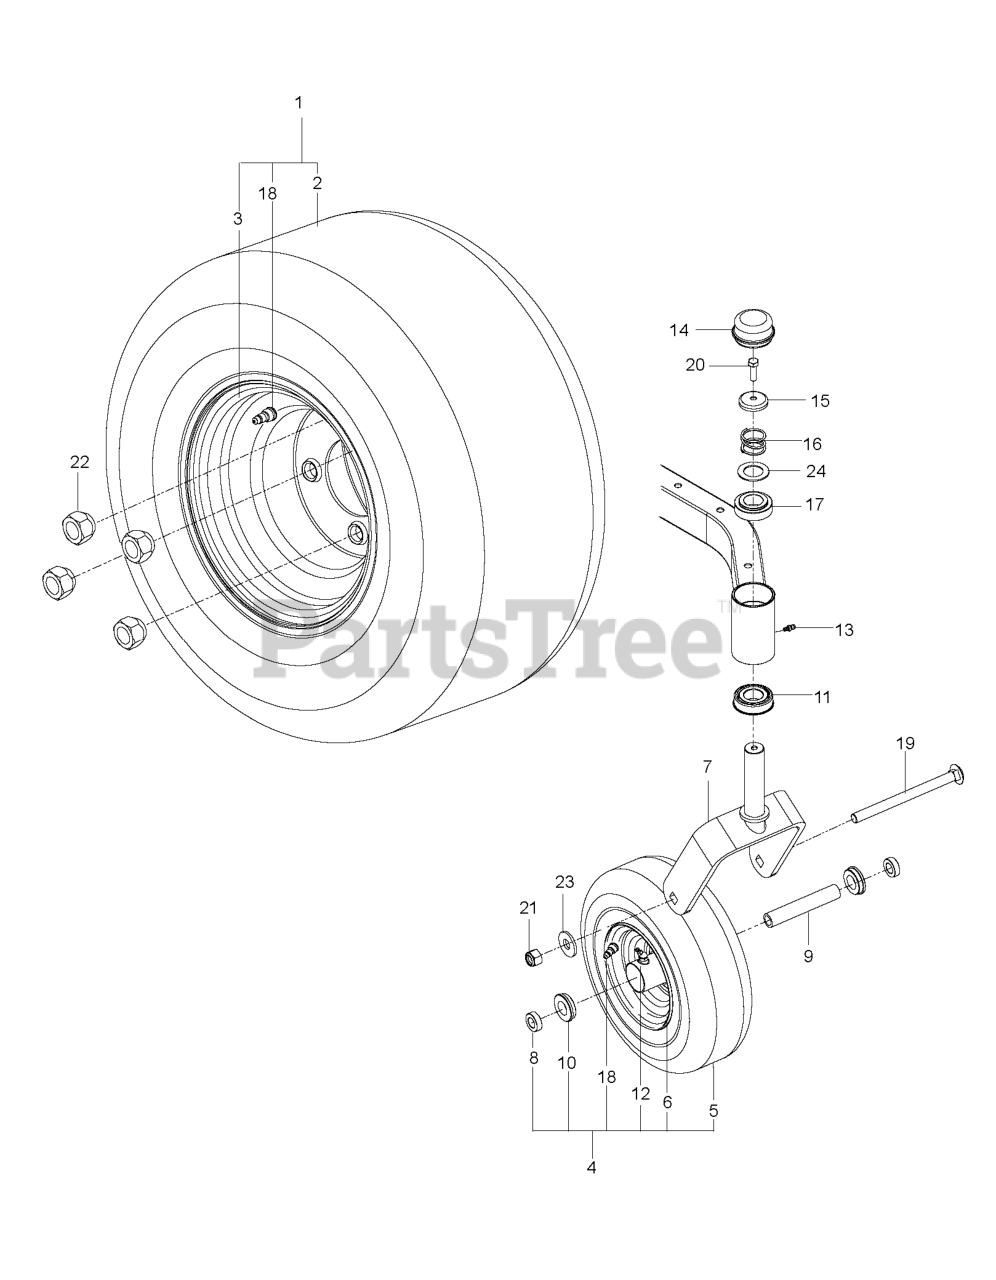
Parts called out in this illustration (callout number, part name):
1	TIRE ASM, 20 X 8-8
2	TIRE 20 X 8, TURF
3	RIM.8X7.W/8".OFFSET.SILVER.ZTR
4	TIRE.CASTER.ASSEM.11X4-5.GR
5	TIRE.11"X4"-5.4PLY.SMOOTH.KEND
7	YOKE.CASTER.ORANGE
8	SPACER, 5/16"
10	BUSHING, WHEEL, 3/4"
11	BEARING FLANGED
12	ZERK
13	ZERK, 3/16, DRIVE IN
14	GREASE CAP
15	CASTER.PLUG
16	SPRING, CASTER
17	BUSHING, CASTER
18	VALVE STEM TR-412
19	RHSNB 1/2-13 X 6.50 GR2 ZD
20	BOLT.FIN.HEX.5/16-18UNC X 1.00
21	NUT 1/2-13 HEX CNTRLK GR 5 ZD
22	LUG NUT 1/2F
23	WASH USS FLAT 1/2
24	WASHER, 1.025 ID X 1.64
